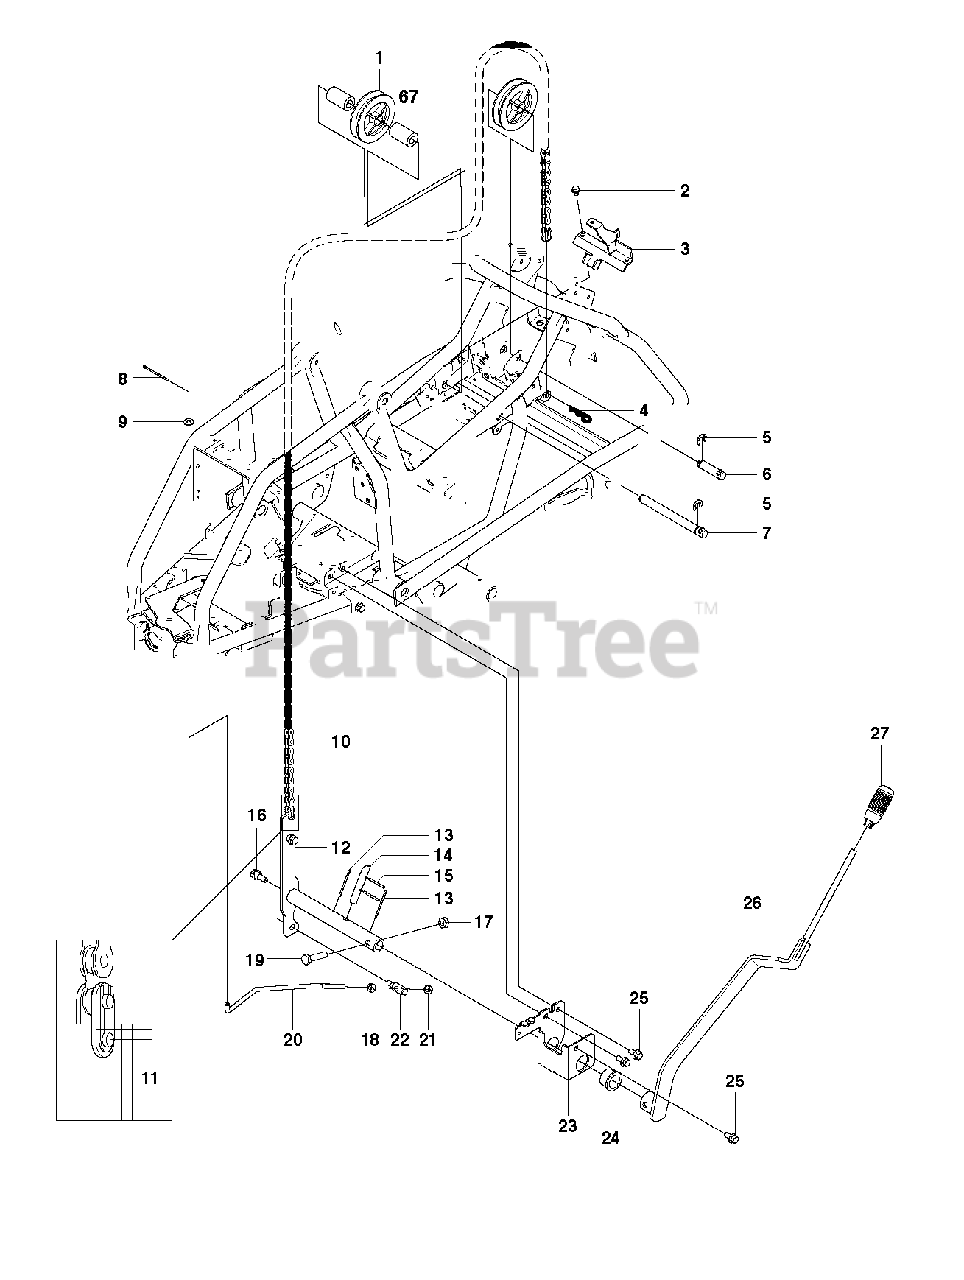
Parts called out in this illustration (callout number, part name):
5	LOCK RING
8	SPLIT PIN
9	WASHER BRB 8.4X17
13	COTTER PIN
14	RP PIN
18	NUT
21	LOCKNUT M8
24	BUSH
